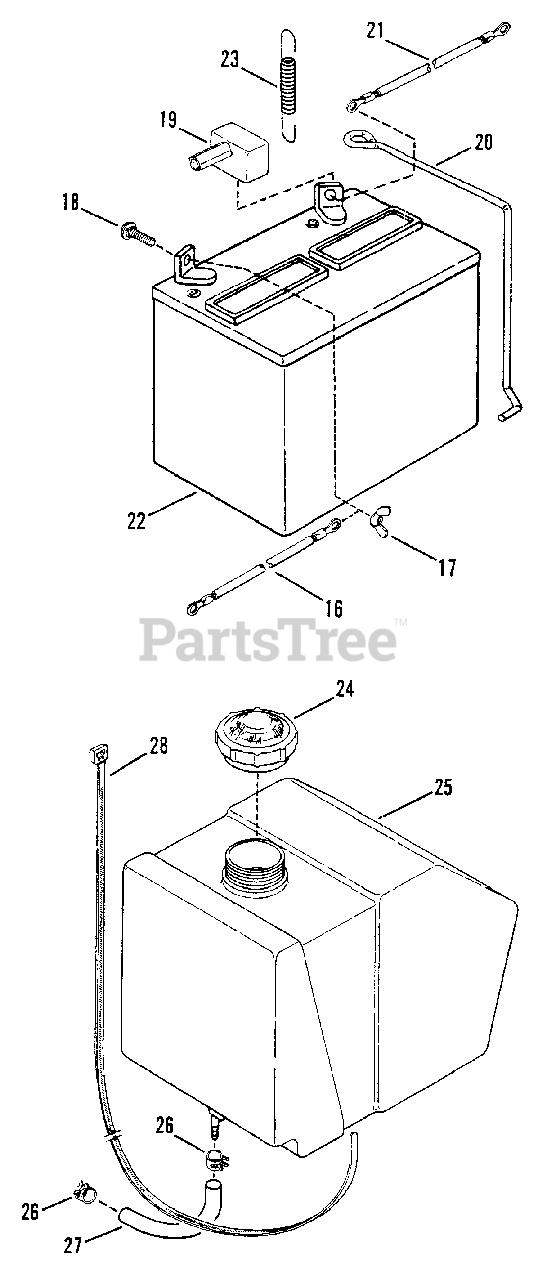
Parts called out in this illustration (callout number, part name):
16	CABLE, Negative Terminal
17	NUT, 1/4-20 Wing
18	BOLT, 1/4-20 x 3/4" Short Neck Carriage
19	COVER, Positive Terminal
20	CLAMP, Battery
21	CABLE, Positive Terminal
22	KIT, Battery (12 Volt)
23	SPRING, Battery Bracket
24	CAP, Fuel Tank
25	TANK, Fuel
26	CLAMP, Fuel Line
27	LINE, Fuel (5" Long)
28	TIE, Cable (Fuel Tank Hold Down)
